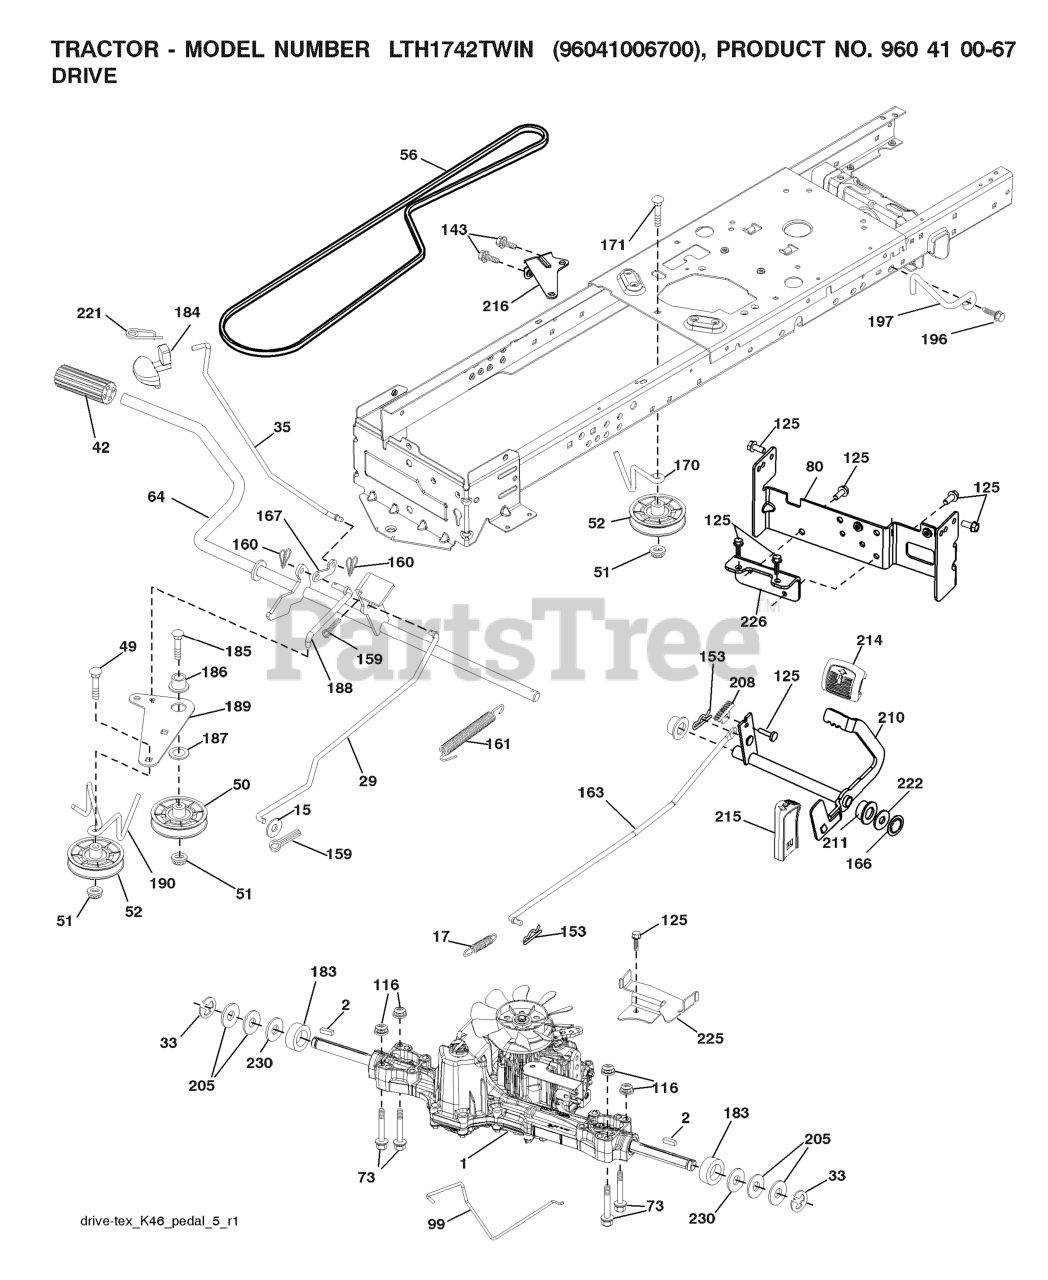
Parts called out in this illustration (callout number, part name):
2	SQUARE KEY
15	WASHER
17	SPRING.BRAKE.K46.GREEN
29	ROD.BRAKE.K46
35	ROD.CNTRL.PARK.PREDATOR.LT.TEX
42	PEDAL COVER T
50	IDLER.FLAT.910.OFFSET
51	NUT LOCK FLG 3/8-16 UNC
52	IDLER.V-GROOVE.910.OFFSET
56	V-BELT.MOWER.92.40.42/K46
64	SHAFT.ASM.PEDAL.BRK.CNTR
73	BOLT HEX 5/16-18 GR 5
80	STRAP TORQUE
99	ROD ASM BYPASS
116	NUT LOCK HEX FLANGE 5/16-18
125	SCREW
143	Screw 5/16-18 x 1/2 Hex, Self Tapping 5/16-18 x 1/2
153	RETAINER M
159	COTTER PIN
160	RETAINER CLIP
161	SPRING, RETURN LT
163	ROD.CONTROL.PEDAL.K46
166	NUT.PUSH.625.2006
167	LATCH.BRAKE.SPRING
169	BOLT HEX 5/16-18 GR 5
170	KEEPER.V-IDLER.CENTER.
183	SPACER AXLE
184	HANDLE PARKING BRAKE
186	SPACER.RETAINER
187	WASHER 12/32X2X10GA
188	RP.LINK.CLUTCH.GROUND.DRIVE
189	BELLCRANK.GROUND.DRIVE.TEX.
190	KEEPER.BELLCRANK.DRIVE
196	SCREW 3/8-16X1
197	LINK.CLUTCH.ANIT-ROTAT
210	ROCKER.ASM.PEDAL.CONTR
211	BEARING.NYLON
214	PEDAL.FORWARD.TEX.GT.4
215	PEDAL.REVERSE.TEX.GT.4
216	BRACKET.PULLEY.IDLER.W/TEX
221	RETAINER.SPRING.CLIP.H
222	WASHER 21/32 X 1-1/4 X 10 GA.
225	KEEPER.BELT.TRANSAXLE.K46
226	BRACKET.MOUNT.TORQUE.K46.TLT
230	WASHER.HARDENED
